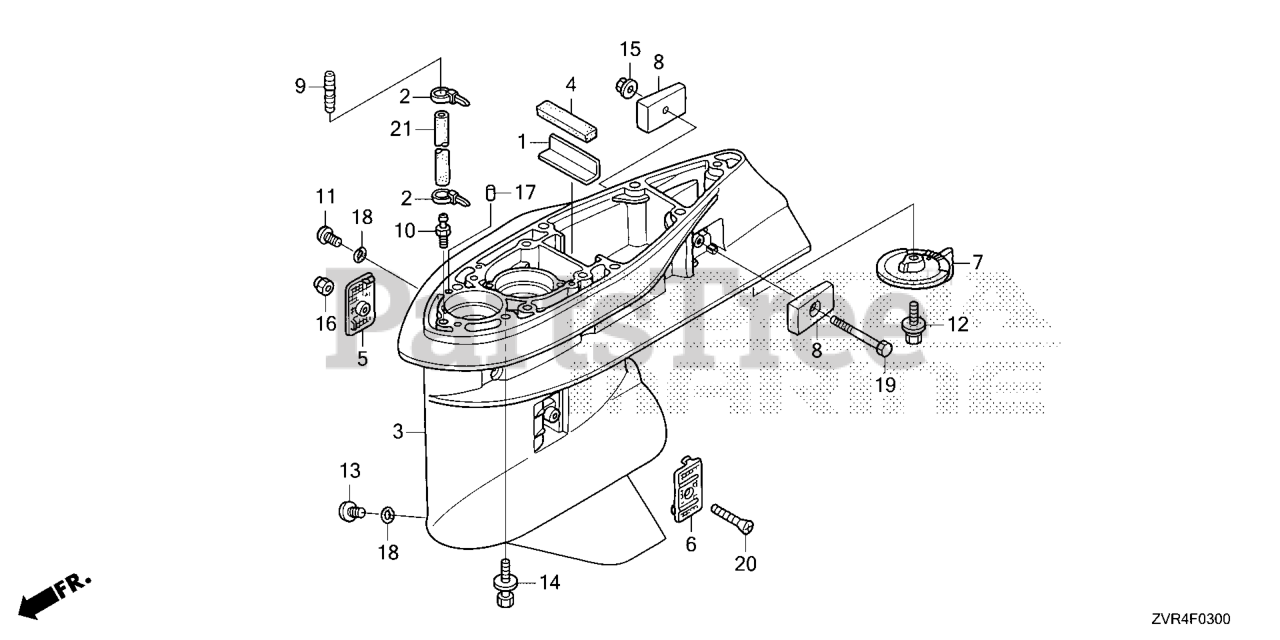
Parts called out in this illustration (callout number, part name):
1	PLATE, RUBBER SETTING
2	BAND, WIRE
3	CASE, GEAR *NHB14M* (AQUA MARINE SILVER METALLIC)
3	CASE,GEAR*NH565*
4	GROMMET, GEAR CASE
5	SCREEN, R. WATER
6	SCREEN, L. WATER
7	TAB, TRIM *NHB14M* (AQUA MARINE SILVER METALLIC)
7	TAB, TRIM *NH565* (GRAND PRIX WHITE)
8	METAL, ANODE
9	END, NIPPLE
10	NIPPLE, SENSOR
11	BOLT, OIL CHECK
12	BOLT-WASHER (10X32)
13	BOLT, DRAIN PLUG
14	BOLT-WASHER (10X40)
15	NUT, SELF-LOCK (6MM)
16	NUT, SELF-LOCK (5MM)
17	PIN, DOWEL (6X10)
18	O-RING (6.9X1.45)
19	BOLT, HEX. (6X50)
20	SCREW, OVAL (5X50)
21	BULK HOSE, VACUUM (5X3000) (5X250)
